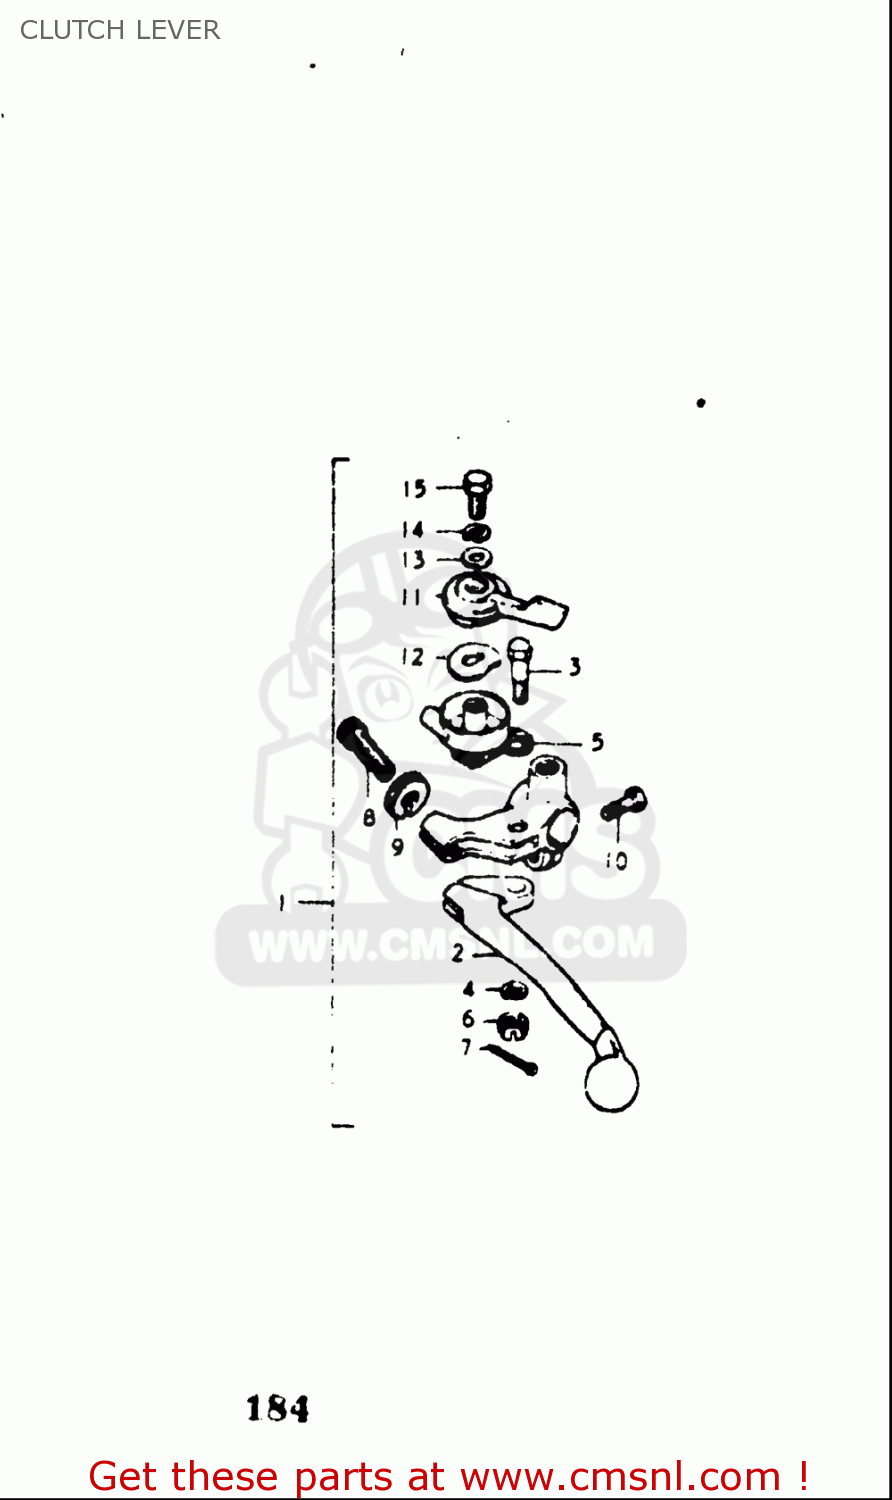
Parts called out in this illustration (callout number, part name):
1	LEVER ASSY,CLUTCH
2	LEVER,CLUTCH
3	BOLT,LEVER PIVOT
4	WASHER,LOCK
6	NUT,LEVER FITTNG
7	PIN 16X20
8	ADJUSTER,CABLE
9	NUT,CABLE ADJUSTER
10	BOLT
11	LEVER
12	WASHER,ADJUSTER
13	WASHER(6.5X16X1)
14	WASHER,LOCK
15	BOLT
